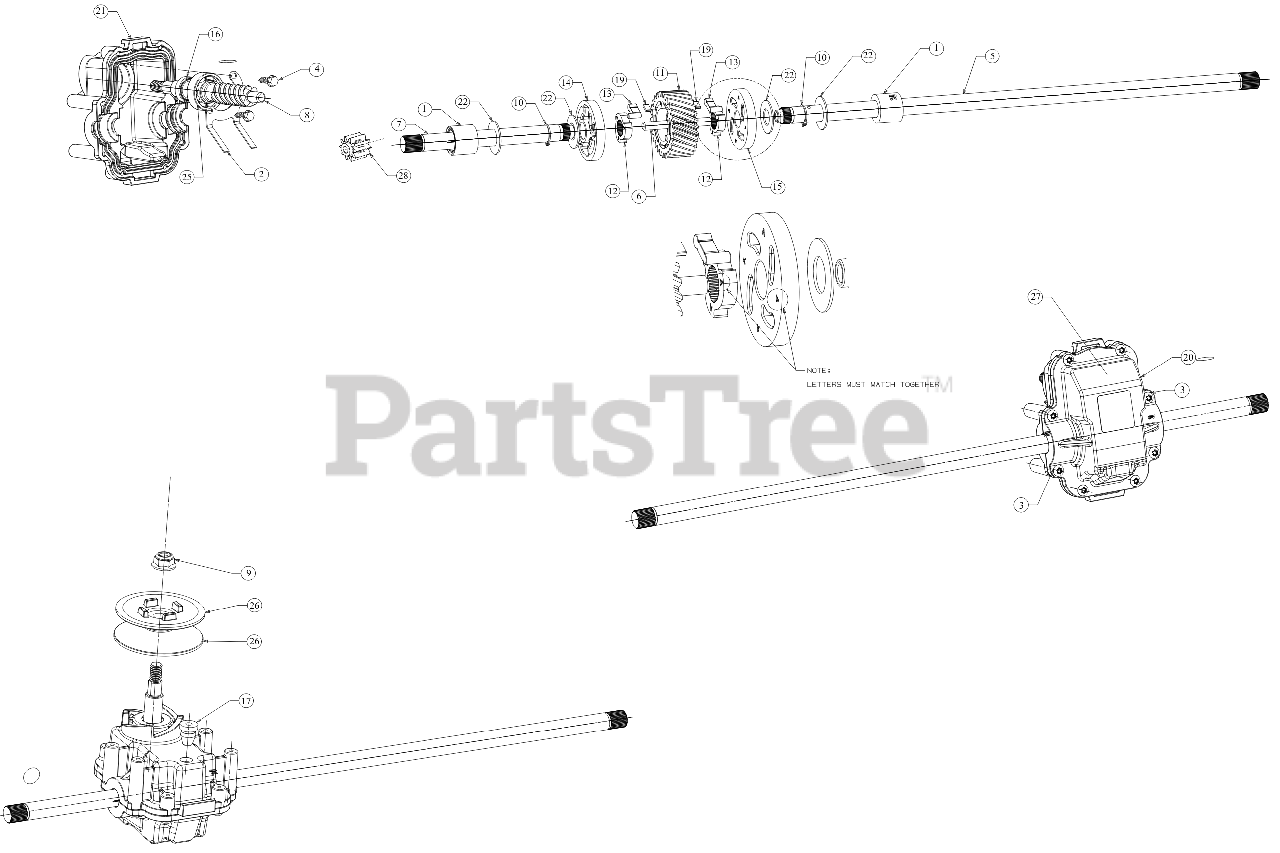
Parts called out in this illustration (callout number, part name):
1	BEARING ASSEMBLY
2	SPRING PLATE
3	SCREW .159 X .610
4	SCREW .159 X .43
5	AXLE SHAFT (RH)
6	PIN
7	AXLE SHAFT (LH)
8	WORM SHAFT
9	FLANGE LOCK NUT 5/16-18
10	SNAP RING FOR .500
11	HELICAL GEAR
12	HUB
13	DRIVE ARM
14	DRAG PLATE (LH)
15	DRAG PLATE (RH)
16	OIL SEAL
17	OIL PLUG
18	THREE BOND SEALANT
19	MAGNET
20	LOWER HOUSING
21	UPPER HOUSING
22	FLAT WASHER .508X1.000X.040
23	TRANSMISSION OIL
24	GREASE
25	BALL BEARING
26	HALF PULLEY 2.50 OD
27	TRANSMISSION COVER
28	SPUR GEAR 9T
